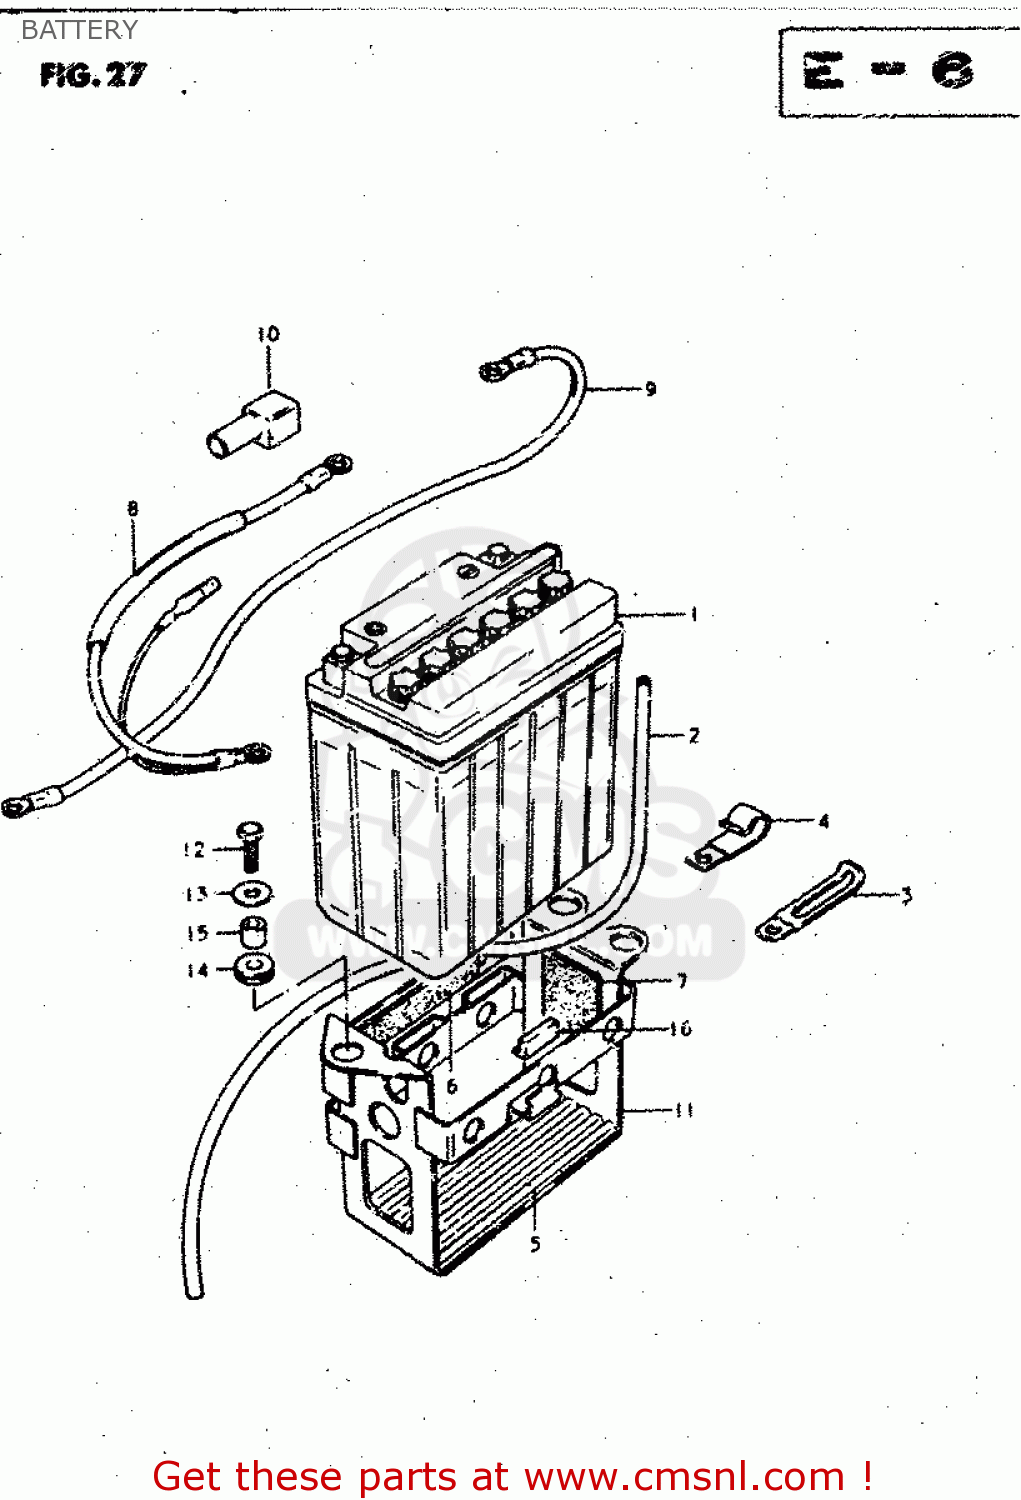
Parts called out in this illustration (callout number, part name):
1	BATTERY ASSY (12V)
2	HOSE,BATTERY EXHAUST
3	CLAMP L:35
4	CLAMP
5	PROTECTOR,BATTERY
6	PROTECTOR(20X90)X4
7	PROTECTOR(170X95X3.0)
8	WIRE,BATTERY PLUS
9	LEAD WIRE,BATTERY(-)
10	CAP,TERMINAL
11	HOLDER,BATTERY
12	BOLT, UPPER
13	WASHER
14	CUSHION
15	SPACER(6.1X9X7.5)
16	CUSHION,FRAME COVER
